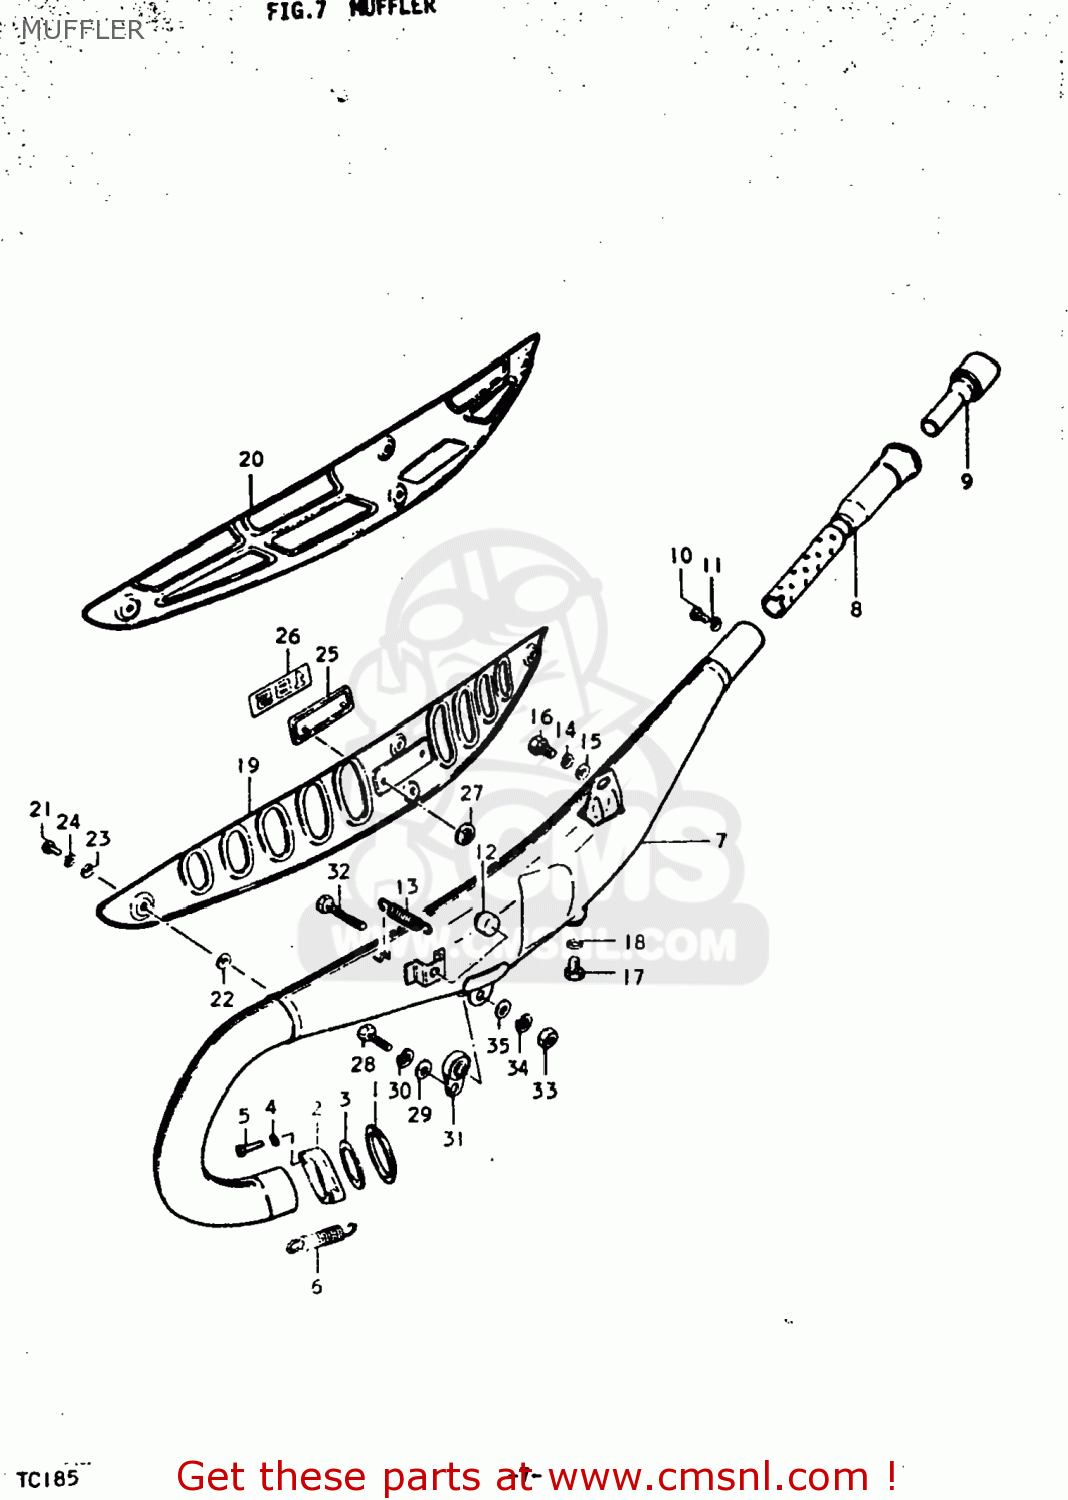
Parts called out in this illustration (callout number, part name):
1	GASKET,EXHAUST PIPE (NAS)
2	CLAMP,EXHAUST PIPE
3	CUSHION,EXHAUST PIPE
4	LOCK WASHER
5	BOLT
6	SPRING
7	MUFFLER ASSEMBLY
8	ARRESTER,SPARK
9	TUBE,MUFFLER CLEAN OUT
10	SCREW(6X8)
11	LOCK WASHER
12	CUSHION(11.5X22X20)
13	SPRING
14	LOCK WASHER
15	WASHER (8.5X18X2)
16	BOLT
17	BOLT 10X9
18	GASKET(10X14X3.6) (NAS)
19	COVER,MUFFLER
20	COVER,MUFFLER
21	SCREW
22	GASKET 6.2X12X1.5 (MCA)
23	WASHER 6MM
24	LOCK WASHER
25	EMBLEM,MUFFLER COVER
26	EMBLEM,MUFFLER COVER
27	NUT
28	BOLT
29	WASHER
30	LOCK WASHER
31	DAMPER,MUFFLER SUPPORT
32	** SUPERSEEDED
33	NUT
34	LOCK WASHER
35	WASHER
